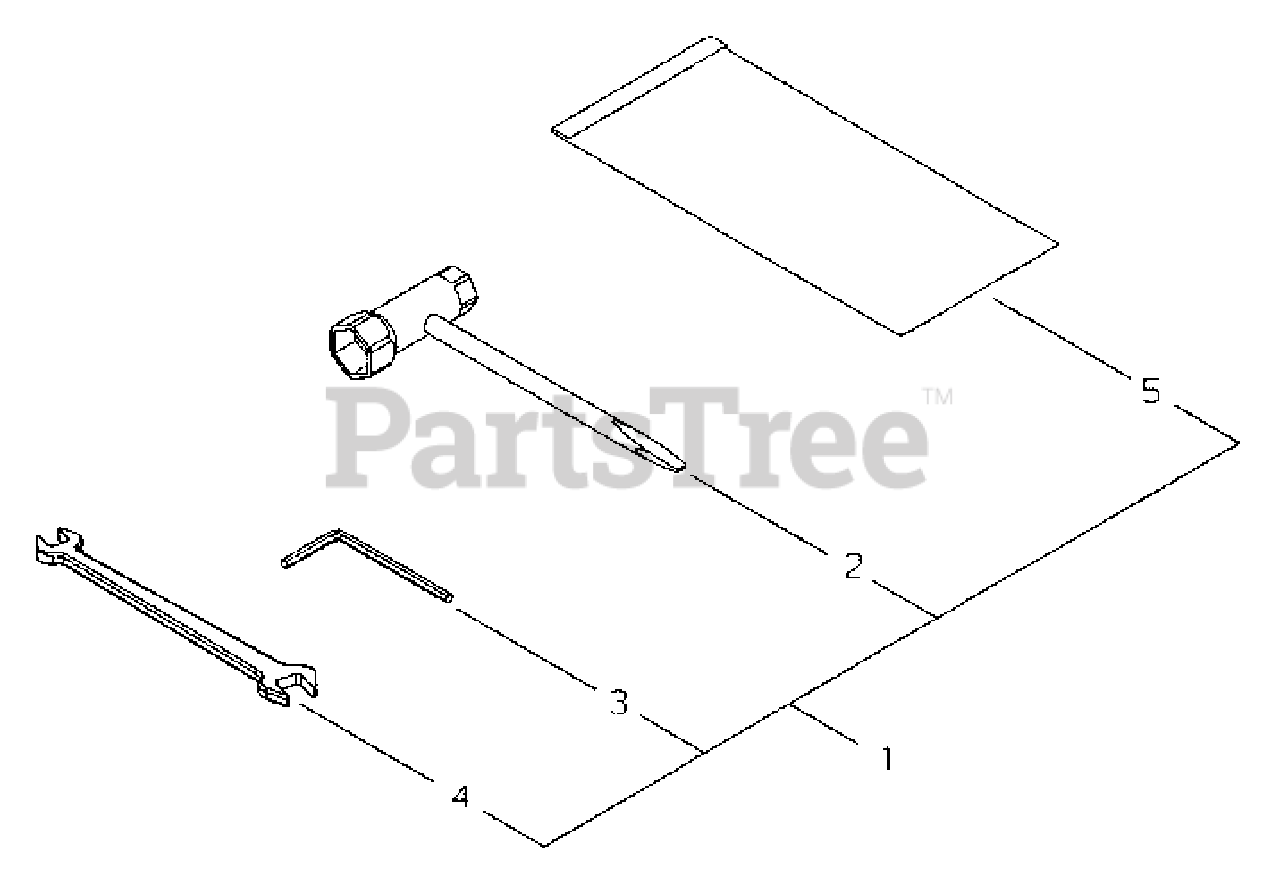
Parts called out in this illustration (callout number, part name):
1	TOOL KIT, SERVICE
2	T-WRENCH 13×19 MM
3	WRENCH, ALLEN 4 MM
4	SPANNER 8×10
5	BAG, TOOL
